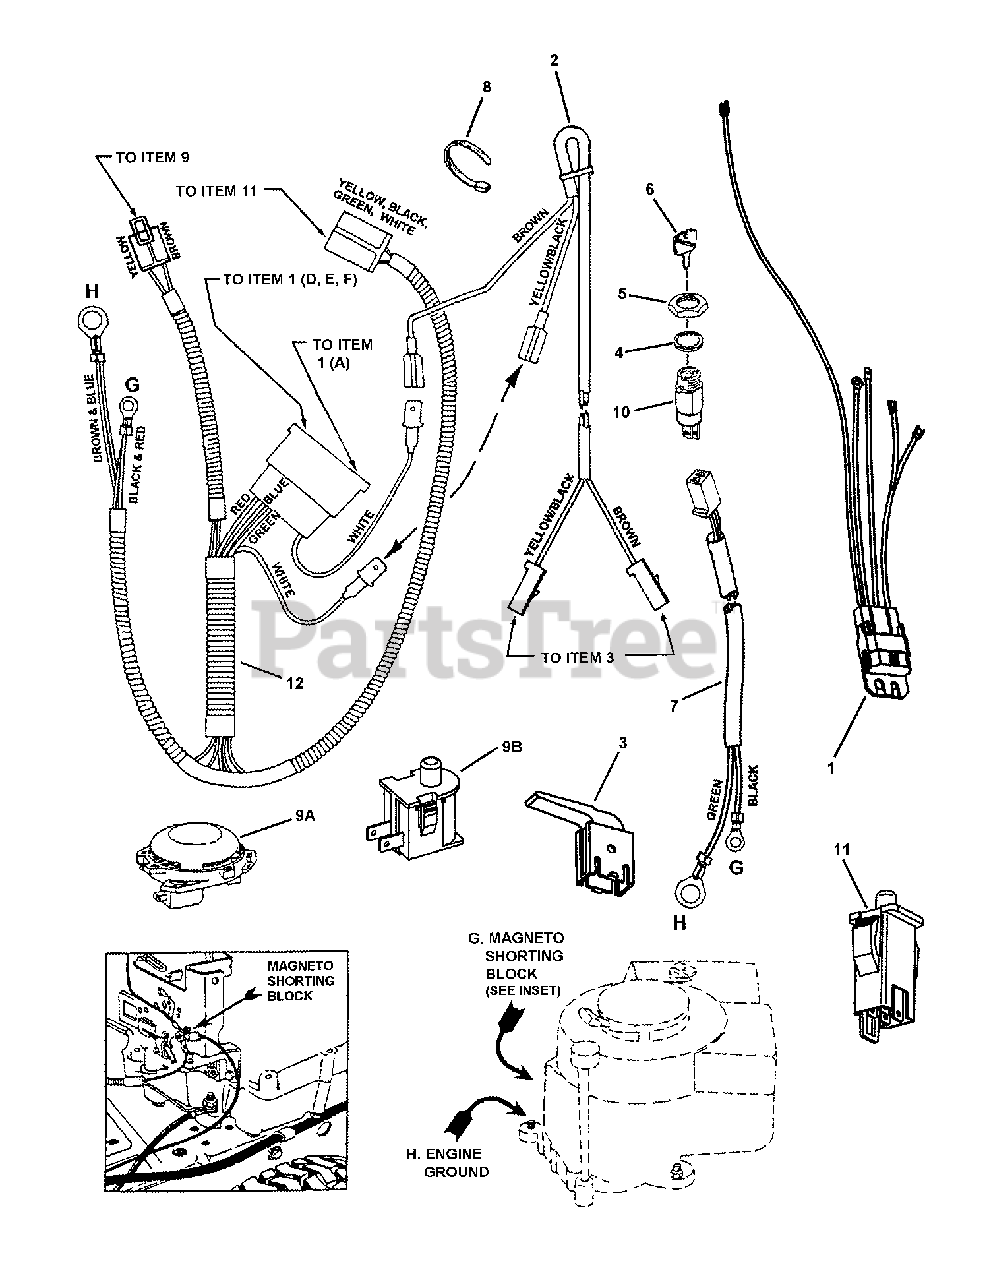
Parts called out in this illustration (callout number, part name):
1	INTERLOCK MODULE, Briggs
2	HARNESS (Deck Interlock Wiring)
3	SWITCH, Deck Interlock (NO)
4	WASHER, 5/8" Internal Tooth Lock
5	NUT, 5/8-32 Hex
6	IGNITION KEY, Pair
7	HARNESS, Ground (Recoil Start)
8	CABLE TIE, 7"
9A	SWITCH, Seat, Quick Mount (NC)
9B	SWITCH, Seat (NC)
10	SWITCH, Ignition (2-Pole) (Recoil Start)
11	SWITCH, Operator Presence Control (OPC) Traction (NC/NO)
12	HARNESS, Operator Presence Control (OPC) Wire
